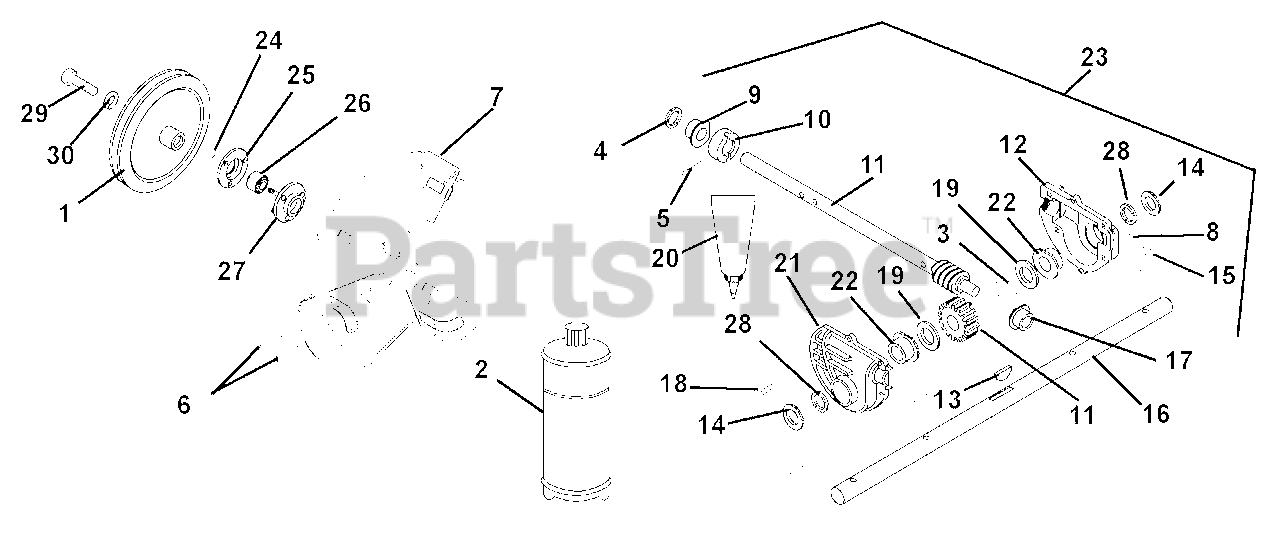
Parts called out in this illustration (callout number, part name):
1	PULLEY, 4L W/HUB, .75 X 8.5
2	ARIENS 16 OZ.BOTTLE OF L2 LUBE
3	BSHG-SLV .755X1.500X.442
4	SEAL-OIL.748X1.378X.276 RBR OD
5	@PIN-GRV .188X1.25 TP E ALLOY
6	PIN-ROLL .250X1.75
7	WELDMENT, IMPELLER,12" 3 BLADE
8	WSHR-FIBER .437X.656X.032
9	BSHG-FLG .750X1.000X.750X1.250
10	THRUST COLLAR, .75" ID
11	SHAFT AND WORM GEAR ASSEMBLY
12	GEARCASE CASTING, MACHINED LH
13	KEY-WDRF .188X.625X.25 SAE 61
14	@WSHR-FL-STL.812X1.50X.135YWZC
15	SCR-TAP .38-16X.75 ROLOK YZ WX
16	SHAFT, RAKE - 24" (.750 DIA)
16	SHAFT, RAKE - 20" (.750 DIA)
17	BSHG-FLG .502X1X.750
18	@SCR-TAP .25-20X1.00 HWH TR YZ
19	WSHR-HDND-THRST .755X1.40X.062
20	LOCTITE 518 GASKET--6ML TUBE
21	GEARCASE CASTING, MACHINED RH
22	BSHG-FLG .753X1.127X.500X1.501
23	GEARCASE, 24" ALUM, SMALL CD
23	GEARCASE, 20" ALUM, SMALL CD
24	@NUT-LK-CTR .25-20 YWZC
25	BEARING FLANGE
26	BRG-BALL .750X1.750X.50
27	BEARING FLANGE
28	SEAL-OIL .750X1.375X.250
29	BLT-HEX .31-24X1.0 GR5 YZ EP80
30	WSHR-LK .312X.097 HVY YWZC
